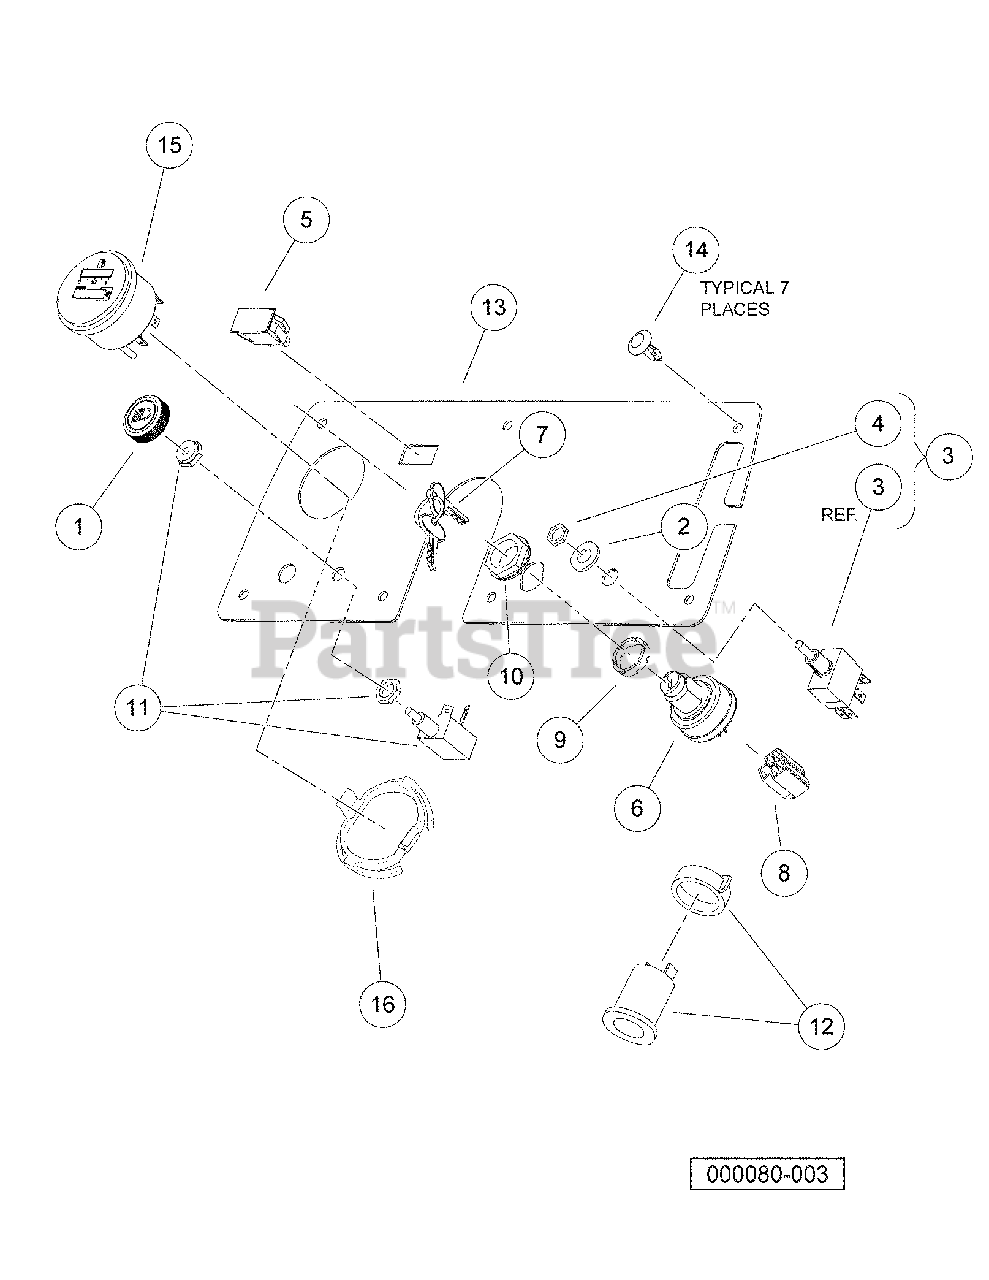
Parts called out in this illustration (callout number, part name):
1	Knob, Light Switch
2	Washer, 7/16 Flat
3	Toggle Switch
4	Nut, Toggle Switch
5	Light, Oil
6	Key Switch 12v Key Start
8	Connector, 5 Way, Female
9	Spacer, Keyswitch
10	Nut, Key Switch
11	Switch, Light
12	Receptacle, Accessory
13	Panel, Instrument - Gas
14	Rivet, Removable, Tuflok 1/4"
15	Gauge Fuel-hour Sep Gnd
16	Clip, Meter, Round
